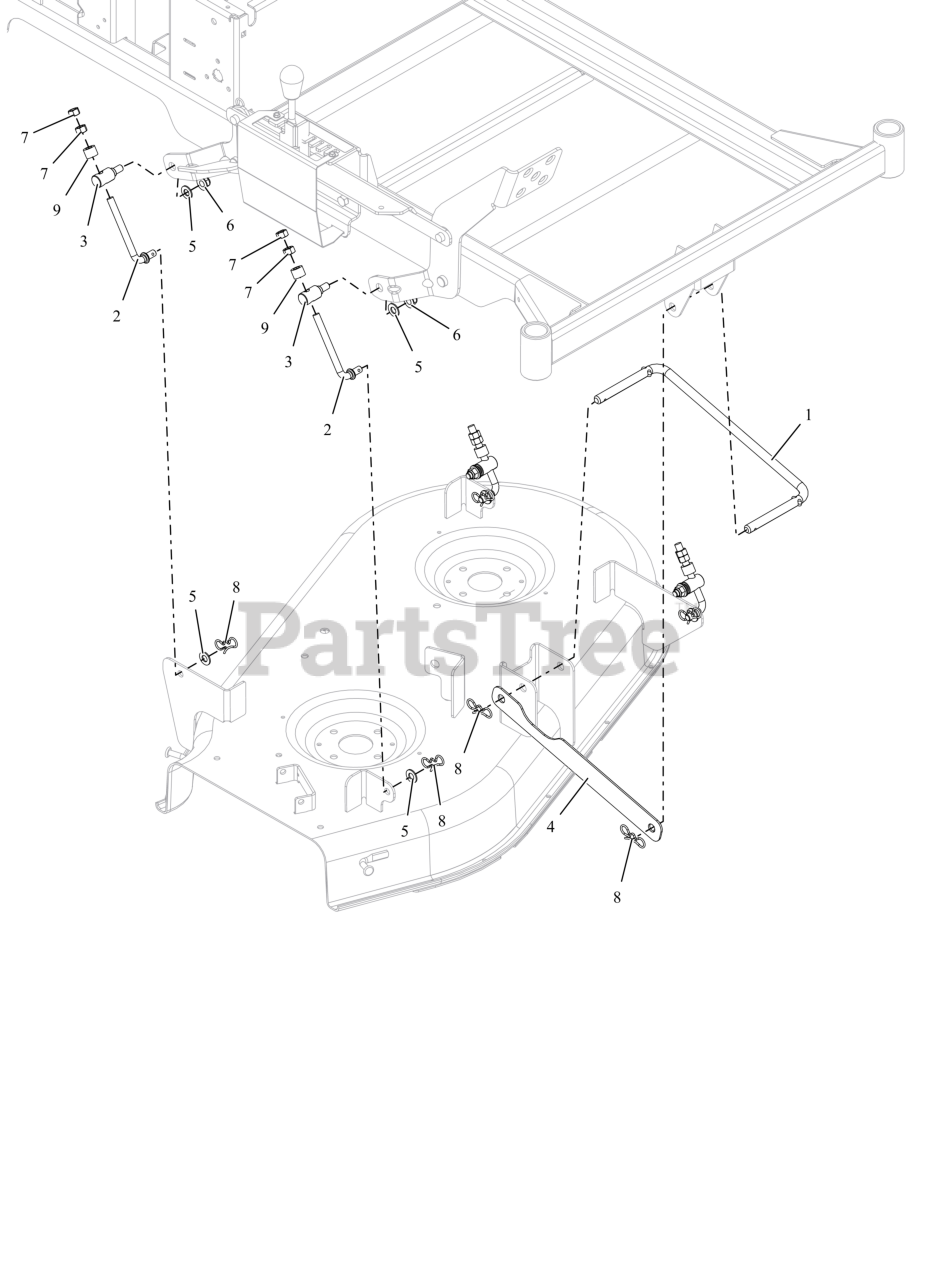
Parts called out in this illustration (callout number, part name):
1	WIREFORM- DRAG LINK
2	WIREFORM- DECK ADJUSTMENT
3	TRUNNION- DECK ADJUSTER
4	STRAP- DRAG LINK
5	WSHR,FLT .406X.812X.065 ZCC
6	NUT,NYL-FLG .38-16 GF ZCC
7	NUT-STD .375-16 G2 ZCC
8	PIN, BOWTIE .091X1.875 ZCC
9	BSHG-SLV .391X.688X.52 PM
